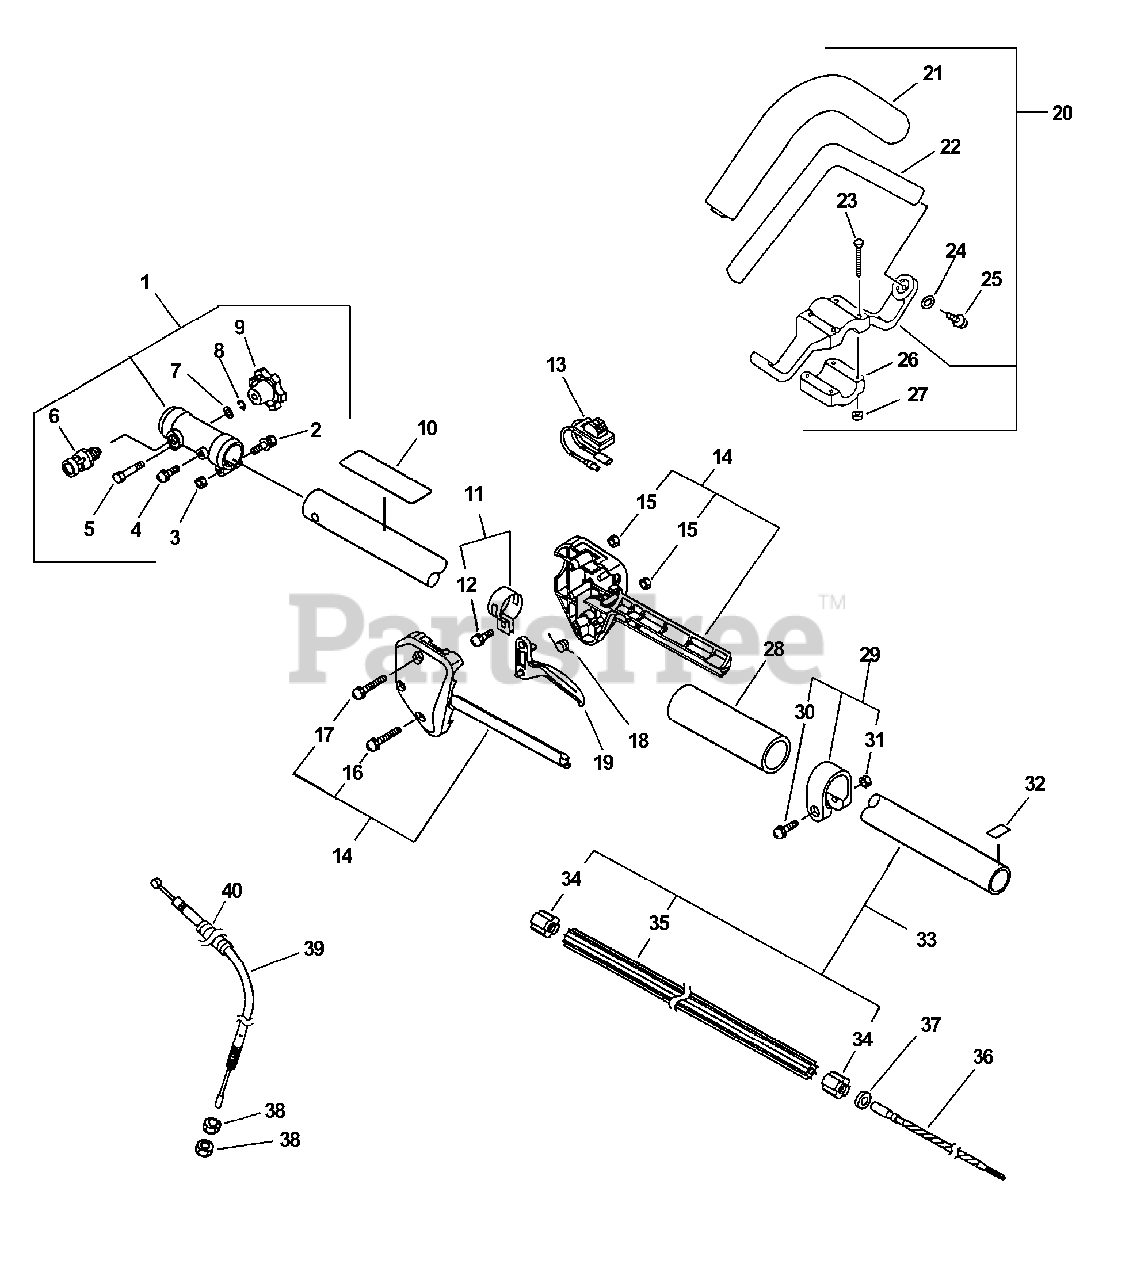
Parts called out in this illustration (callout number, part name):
1	COUPLER ASSY
2	BOLT 5×30
3	NUT M5
4	SCREW 5×12
5	BOLT 5×35 SP
6	LATCH ASSY
7	WASHER, FLAT 5.5×10×0.8
8	WASHER, SPRING 5
9	KNOB, FASTENER
10	LABEL, CAUTION
11	CLAMP KIT
12	SCREW 5×14
13	SWITCH ASSY, ON-OFF
14	HANDLE KIT, CONTROL
15	NUT M5
16	SCREW 5×25
17	SCREW 5×35
18	SPRING, TORSION
19	TRIGGER, THROTTLE
20	FRONT HANDLE ASSY
21	GRIP, HANDLE
22	HANDLE, SUPPORT
23	SCREW 5×35
24	WASHER, FLAT 5.5×10×0.8
26	BRACKET, HANDLE - LOWER
27	NUT M5
28	GRIP, HANDLE
29	CLAMP KIT
30	SCREW 5×28
31	NUT M5
32	LABEL - ALIGNMENT
33	MAIN PIPE ASSY
35	LINER - FLEXIBLE
36	DRIVESHAFT - FLEXIBLE
39	CABLE, THROTTLE
40	TUBE
